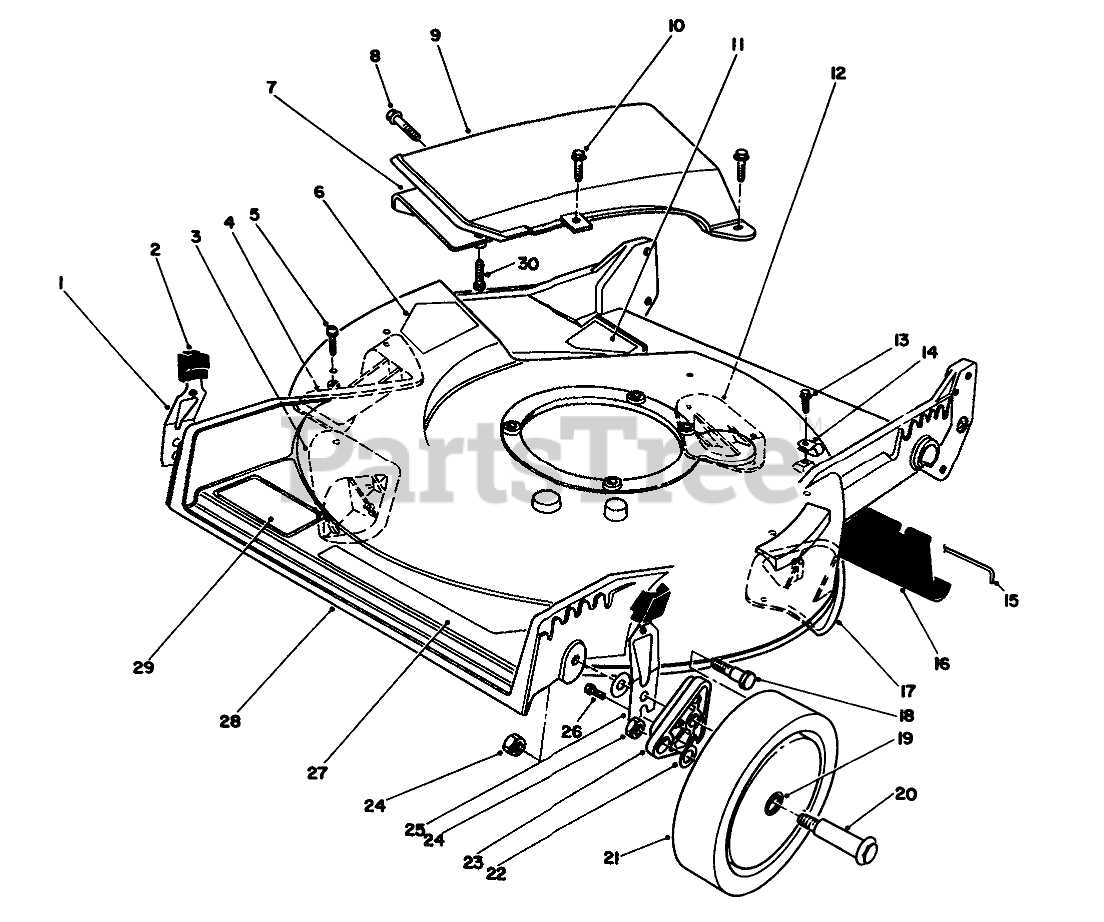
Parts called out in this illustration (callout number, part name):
1	RH SPRING ARM ASSEMBLY
2	KNOB-ARM
3	KICKER
4	KICKER
5	#8 X .625" PHILPS PAN H
6	DECAL-DANGER
7	Deflector-Recycler
8	SCREW AND WASHER ASM
9	Cover Assembly (Incl. Ref #7 & 19)
10	SCREW-HWH
11	DECAL - DANGER
12	PLATE-KICKER
13	SCREW-HWHTF
14	CLAMP-R
15	ROD-SHIELD
16	SHIELD-TRAILING
17	KICKER
18	SCREW-SHOULDER
19	BUSHING
20	WHEEL BOLT
21	Wheel & Tire Assembly (Incl. Ref. #19)
22	WASHER
23	ARM-PIVOT, FRONT
24	Nut
25	LH SPRING ARM ASSEMBLY
26	SCREW-HWH
27	DECAL - DECK
28	Housing Assembly (Incl. Ref. #3-6, 12, & 17)
29	DECAL
30	Screw-Pan Hd.
